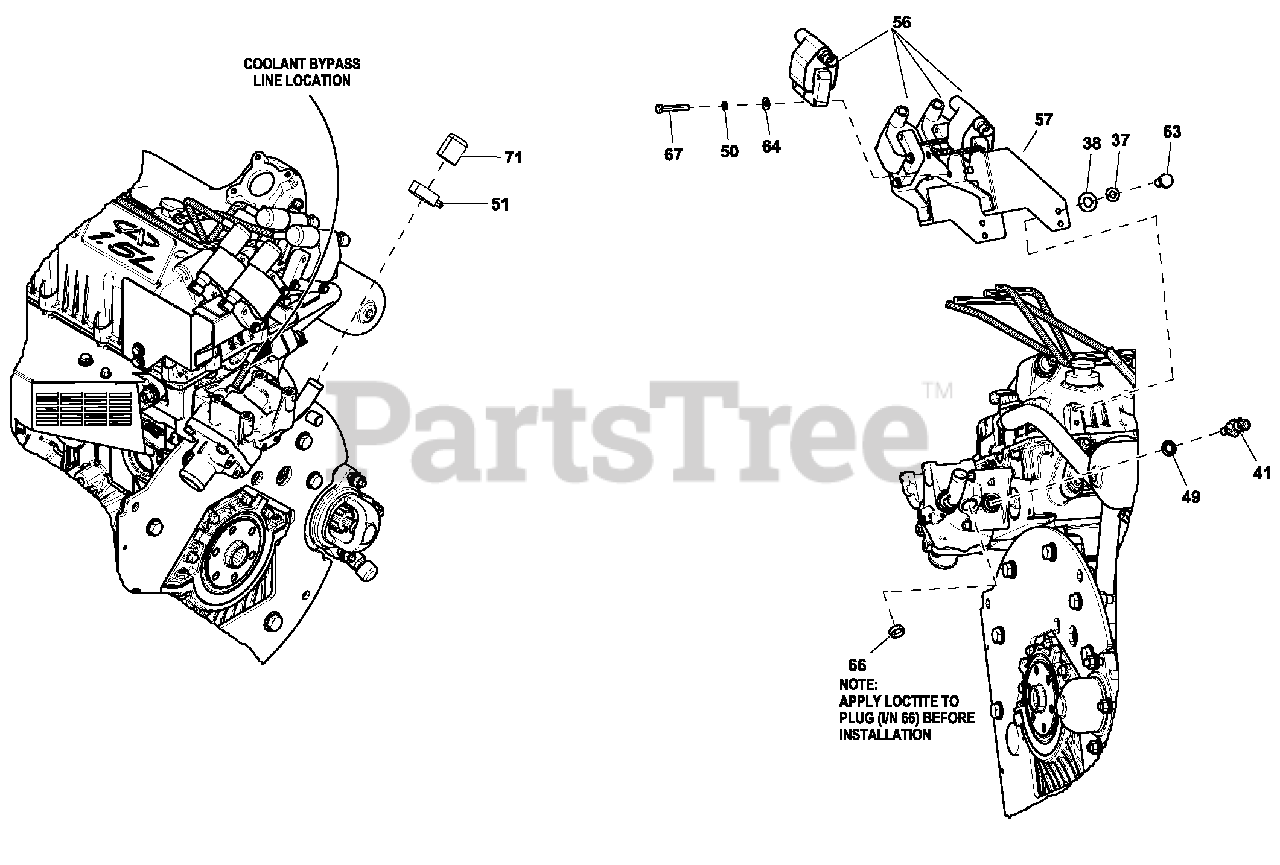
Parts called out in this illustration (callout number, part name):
37	WASHER LOCK M6-1/4
38	WASHER FLAT 1/4-M6 ZINC
41	TEMPERATURE SENDER DELPHI M12
49	WASHER, NITRILE SEAL M12
50	WASHER LOCK #10
51	CLAMP HOSE #10.56-1.06
56	COIL2.4L G2 IGNITION
57	ASSY BRACKET COIL 1.5LG11
63	SCREW HHC M6-1.0 X 16 C8.8
64	WASHER FLAT #10 ZINC
66	PLUG FREEZE
67	SCREW HHM #10-32X1-1/4
71	CAP ANTIFREEZE 5/8"ID X 1.2"LG
